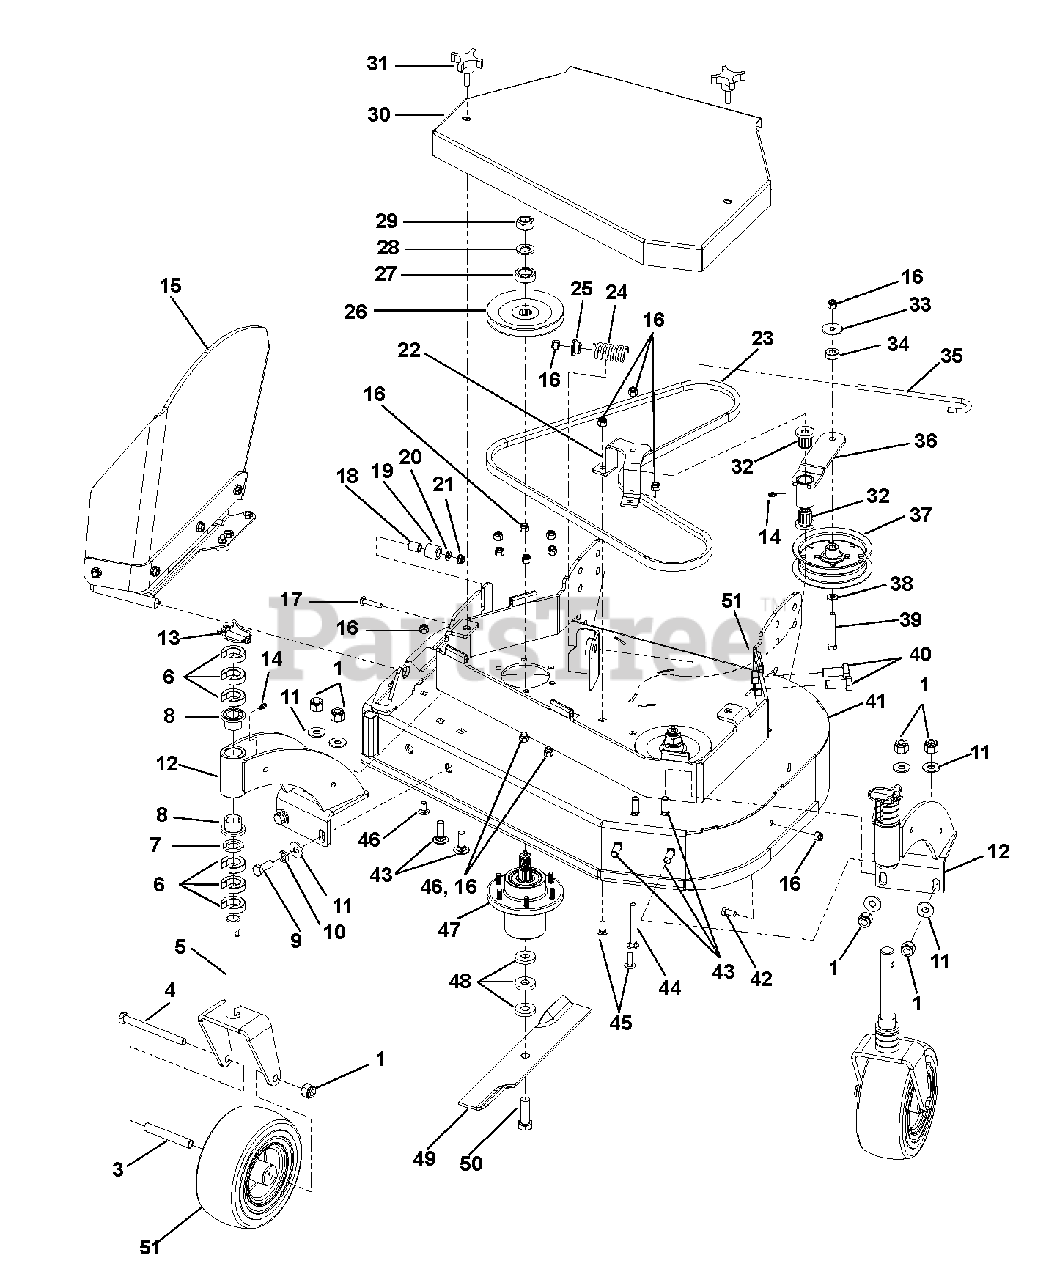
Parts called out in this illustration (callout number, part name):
1	Locknut, .50-13 Nyloc
2	Assembly, Wheel and Tire 9 x 3.5
3	Tube, Caster Axle
4	Bolt, .50-13 x 5.50 Hex Grade 5
5	Weldment, Caster Yoke w/ EverRide Paint
6	C-Spacer, 1.00 x 1.77 x .500
7	Bushing, 1.03 x 1.50 x .179
8	Bearing, Flange 1.00 x 1.25 x 1.00
9	Bolt, .50-13 x 1.25 Hex Grade 5
10	Washer, .500 Medium Spring Lock
11	Washer, .438 Regular Flat
12	Weldment, Strut Front FXWLK w/ EverRide Paint
13	Pin, LNC .438 x 2.00
14	Fitting, .25-28 Straight Grease Zerk
15	Discharge Shield Assembly
16	Locknut, .38-16 Nyloc
17	Bolt, .3125-18 x 1.50 Round Head Square Neck Grade 2
18	Bushing, Straight .407 x .625 x .813
19	Bumper, Rubber .62 x 1.0 x .88 LG
20	Washer, .531 x 1.062 x .095 Flat
21	Nut, .31-18 Nyloc Flange
22	Bracket, Idler
23	Belt, 5L 76.15 Banded
24	Spring, COM 1.22 x .162 x 2.50
25	Keeper, Spring
26	Pulley, V-Belt 5.75 Drive Points
27	Spacer, 1.500 x 1.000 x .510
28	Washer, .75 x 1.313 x .113
29	Locknut, .75-16 Crown
30	Weldment, Shield 32"
31	Knob, .375 x 1.25-4 Prong
32	Bearing, Flange M10 x M25 x M27 Fluted
33	Washer, Flat .375 x 1.50 x .063
34	Bushing, .380 x 1.00 x .410
35	J-Bolt, .375-16 x 7.88
36	Weldment, Idler Arm w/Offset
37	Pulley, Flat 5.0 x .38 w/BRG
38	Washer, .406 x .813 x .065 Flat
39	Bolt, .38-16 x 2.75 Hex Grade 5
40	Bolt, Hex .625-11 1.50 Grade 8
41	Assembly, Deck EverRide 32" with Decals
42	Bolt, .38-16 x .750 Hex Grade 5
43	Bolt, Round Head Square Neck .50-13 x 1.50 Grade 5
44	Bolt, .375-16 x 3.50 Round Head Square Neck Grade 5
45	Bolt, .375-16 x 1.00 Round Head Square Neck Grade 2
46	Bolt, Round Head Square Neck .38-16 x .75
47	Assembly, Spindle Housing
48	Washer Blade
49	Blade, 16.502 Lo-Lift
50	Bolt, .625-11 x 2.00 Hex 8
51	Trim, 1/4" Trim-LOK Edge
